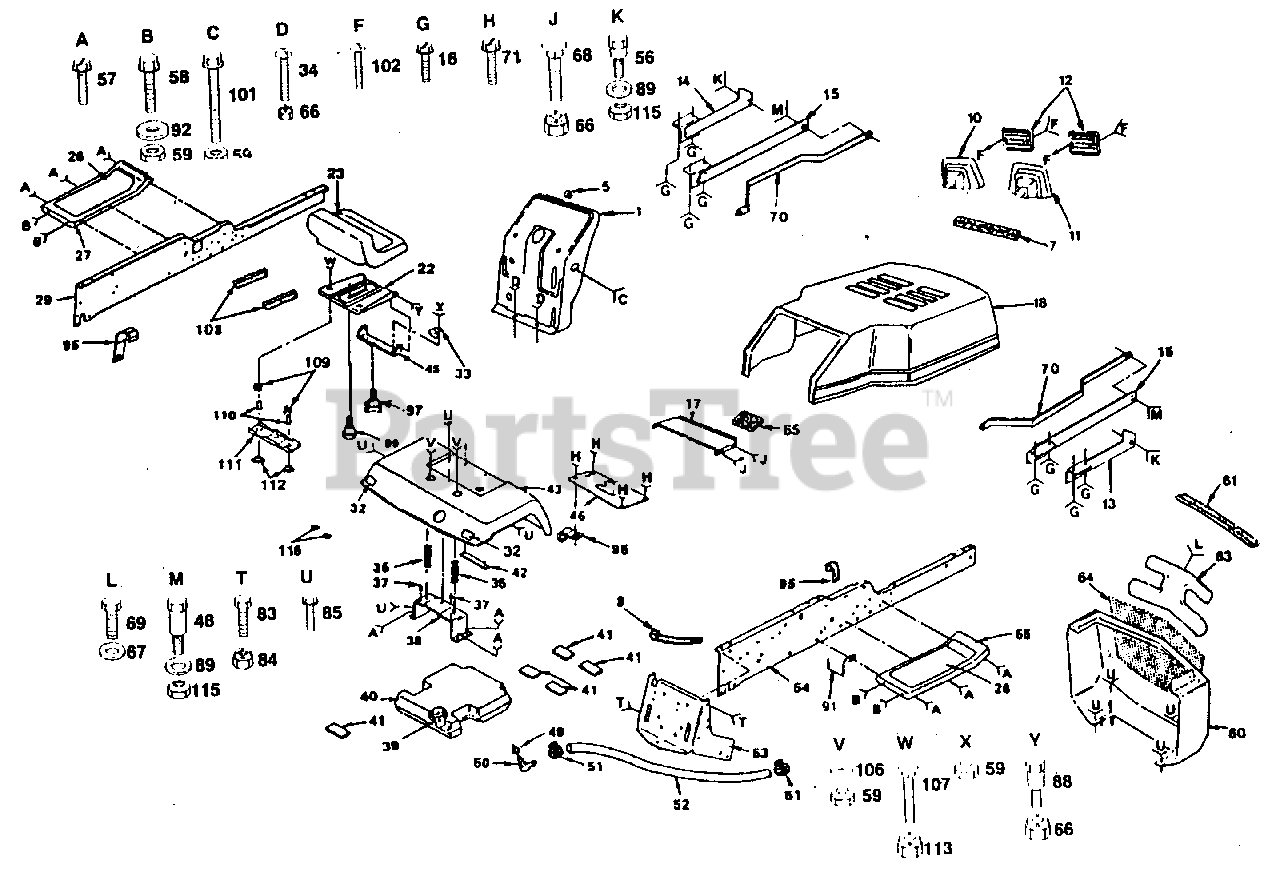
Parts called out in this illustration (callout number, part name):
5	Plug, Dash (AYP part number)
7	Foam, Strip (AYP part number)
8	Cable, Tie (AYP part number)
10	Bezel, L.H. (AYP part number)
11	Bezel, R.H. (AYP part number)
12	Lens (AYP part number)
13	Strap Assembly Hinge R.H. (AYP part number)
14	Strap Assembly Hinge L.H. (AYP part number)
15	Strap Assembly Hinge Rear (AYP part number)
16	Screw, Hex Wsh. Hd. #13-16 x 5/8 (AYP part number)
17	Support, Battery (AYP part number)
18	Hood (AYP part number)
22	Pan, Seat (AYP part number)
23	Seat (AYP part number)
26	Pad, Footrest (AYP part number)
27	Footrest, L.H. (AYP part number)
29	Rail, Frame, L.H. (AYP part number)
32	Reflector, Taillight (AYP part number)
33	Clip, Insulated (AYP part number)
34	Screw, Mach. Hd. 5/16-18 x 3/4 (AYP part number)
35	Spring, Compression (AYP part number)
37	Nut, Push (AYP part number)
38	Bracket, Fender (AYP part number)
39	Cap, Fuel (AYP part number)
40	Tank, Fuel (AYP part number)
41	Pad, Spacer (AYP part number)
42	Strap, Fender (AYP part number)
43	Fender (AYP part number)
45	Bracket, Pivot, Seat (AYP part number)
46	Cover, Shift-Gate (AYP part number)
48	Bolt, Shoulder (AYP part number)
49	Bushing (AYP part number)
50	Stem, Tank Fuel (AYP part number)
51	Clamp, Hose (AYP part number)
52	Fuel Line (AYP part number)
53	Drawbar (AYP part number)
54	Rail, Frame, R.H. (AYP part number)
55	Footrest, R.H. (AYP part number)
56	Bolt, Shoulder (AYP part number)
57	Screw, Hex Washer Thread Rolling 3/8-16 x 3/4 (AYP part number)
58	Bolt, Hex 3/8-16 x 3/4 (AYP part number)
59	Locknut 3/8-16
60	Grill (AYP part number)
61	Foam, Strip
63	Grill, Insert
64	Screen, Grill
65	Foam, Strip (AYP part number)
66	Nut, Crownlock 5/16-18
67	Washer 7/32 x 5/8 x 16 Ga. (AYP part number)
68	Bolt, Carriage 5/16-18 x 3/4
69	Screw, Hex #12 x 1/2 (AYP part number)
70	Brace, Grill (AYP part number)
71	Screw, Hex 1/4-20 x 1/2 (AYP part number)
83	Bolt, Hex 7/16-14 x 1 (AYP part number)
84	Locknut 7/16-14 (AYP part number)
85	Screw, Hex Washer Thread Rolling 3/8 x 16 x 1/2 (AYP part number)
88	Bolt, Shoulder (AYP part number)
89	Washer 9/32 x 1/2 x 16 Ga. (AYP part number)
91	Retainer, Belt, Lower (AYP part number)
92	Washer 13/32 x 13/16 x 17 Ga. (AYP part number)
95	Clip, Insulated (AYP part number)
97	Knob (AYP part number)
99	Bolt, Shoulder 5/16-18 (AYP part number)
101	Bolt, Hex 3/8-16 x 1-1/2 (AYP part number)
102	Screw, Pan Hd. #8-18 x 1/2 (AYP part number)
106	Washer, 13/32 x 1 x 14 Ga. (AYP part number)
107	Bolt, Carr. 1/4-20 x 1-1/4 (AYP part number)
108	Foam, Strip (AYP part number)
109	Spring, Compression (AYP part number)
110	Spacer, Split (AYP part number)
111	Bracket, Switch (AYP part number)
112	Bushing, Snap (AYP part number)
113	Locknut, Flange 1/4-20 (AYP part number)
115	Nut, Crownlock 1/4-20 (AYP part number)
116	Cap, Spring (AYP part number)
